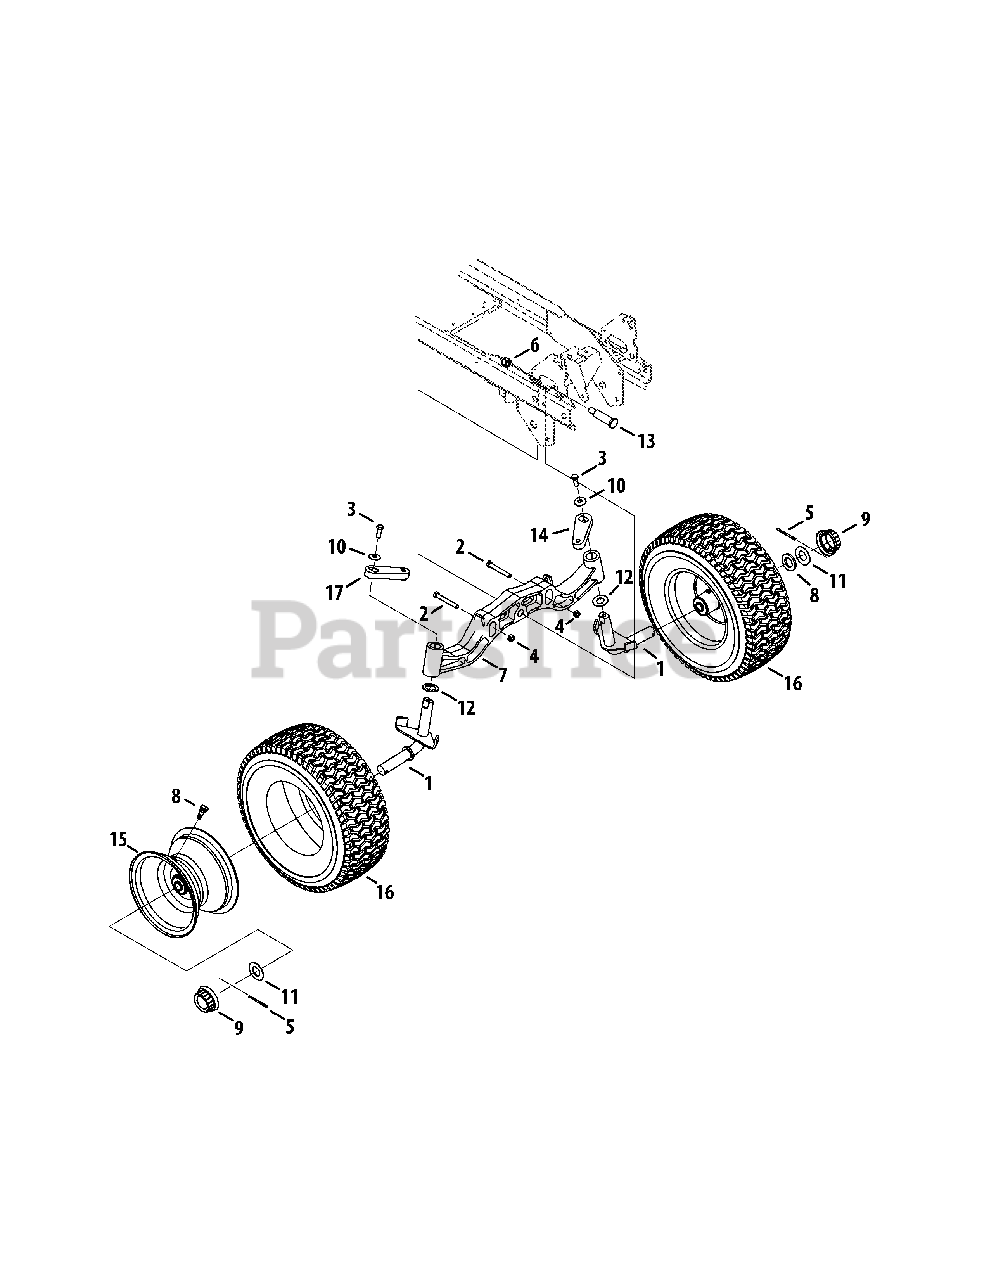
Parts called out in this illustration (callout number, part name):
1	Axle Assembly 1.0 Dai
2	Hex Screw, 3/8-16 x 2.75
3	Hex Cap Screw, 3/8-24 x 1.00
4	Hex Lock Nut, 3/8-16
5	Cotter Pin, 3/16 x 2.0
6	Hex Lock Nut, 1/2-13
8	Tubeless Air Valve
10	Bevel Washer, .390 x 1.130 x .062
11	Flat Washer, 1.05 x 1.92 x .06
12	Thrust Washer, 1.010 x 2.50 x .060
13	Shoulder Screw, .750 x 2.23
14	Steering Arm, LH
15	Rim Assembly, 16.0 x 6.5 x 8
16	Tire, 16.0 x 6.50-8.00
17	Steering Arm, RH
